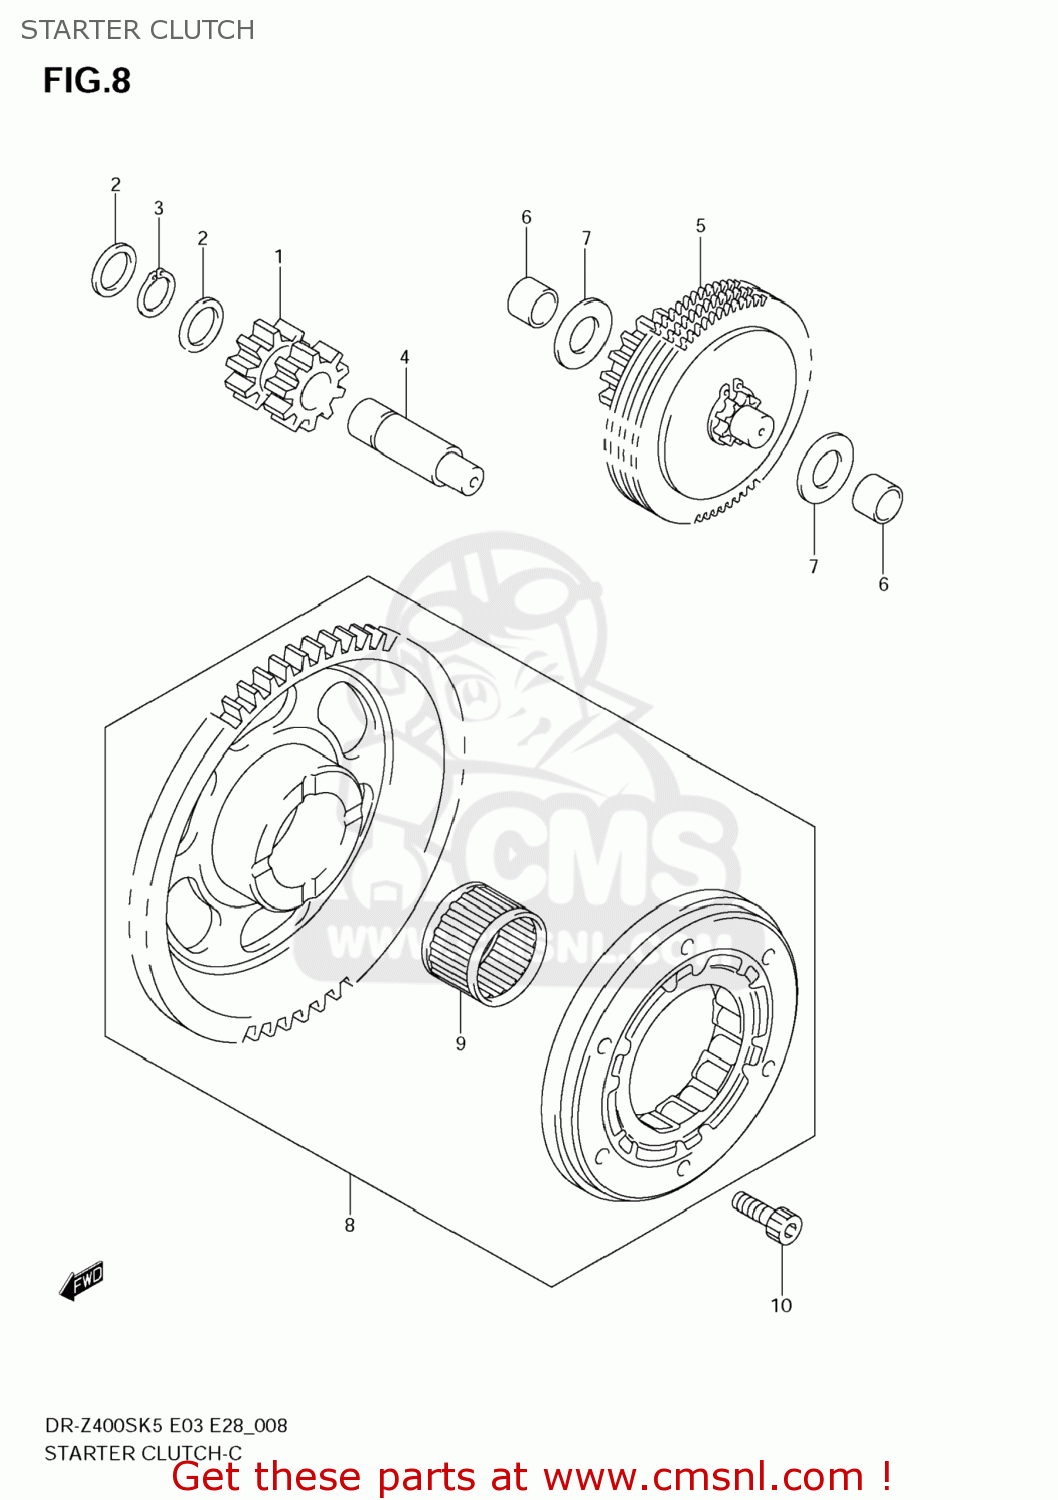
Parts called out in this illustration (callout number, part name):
1	GEAR,STARTER IDLE NO.1
2	SHIM(12X18X0.5)
3	CIRCLIP,12 MM
4	PIN,STARTER IDLE GEAR NO.1
5	LIMITER ASSY,STARTER IDLE GEAR
6	BUSH,LIMITER GEAR SHAFT
7	WASHER
8	CLUTCH SET,STARTER
9	BEARING(25X31X19)
10	BOLT(6X16)
